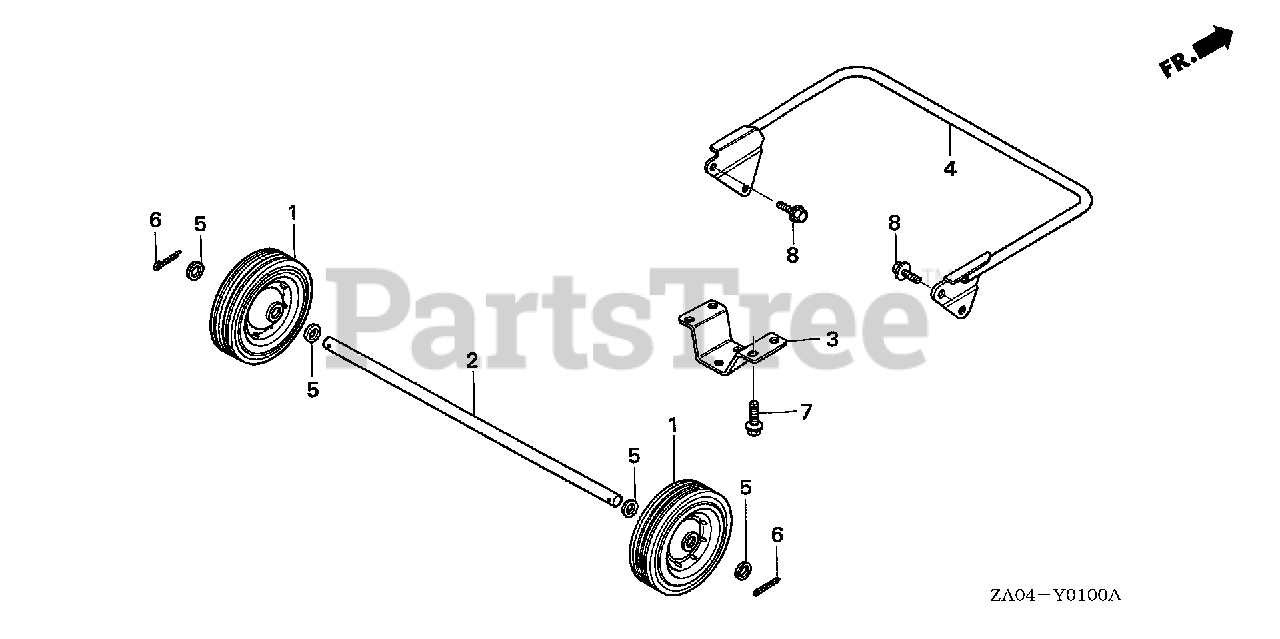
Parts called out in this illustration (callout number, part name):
1	WHEEL (10"X2.75") (GLEASON)
2	SHAFT, WHEEL
3	STAND
4	PIPE, HANDLE
5	WASHER, PLAIN (20MM)
6	PIN, SPLIT (4.0X30)
7	BOLT, FLANGE (6X12)
8	BOLT, FLANGE (8X16)
